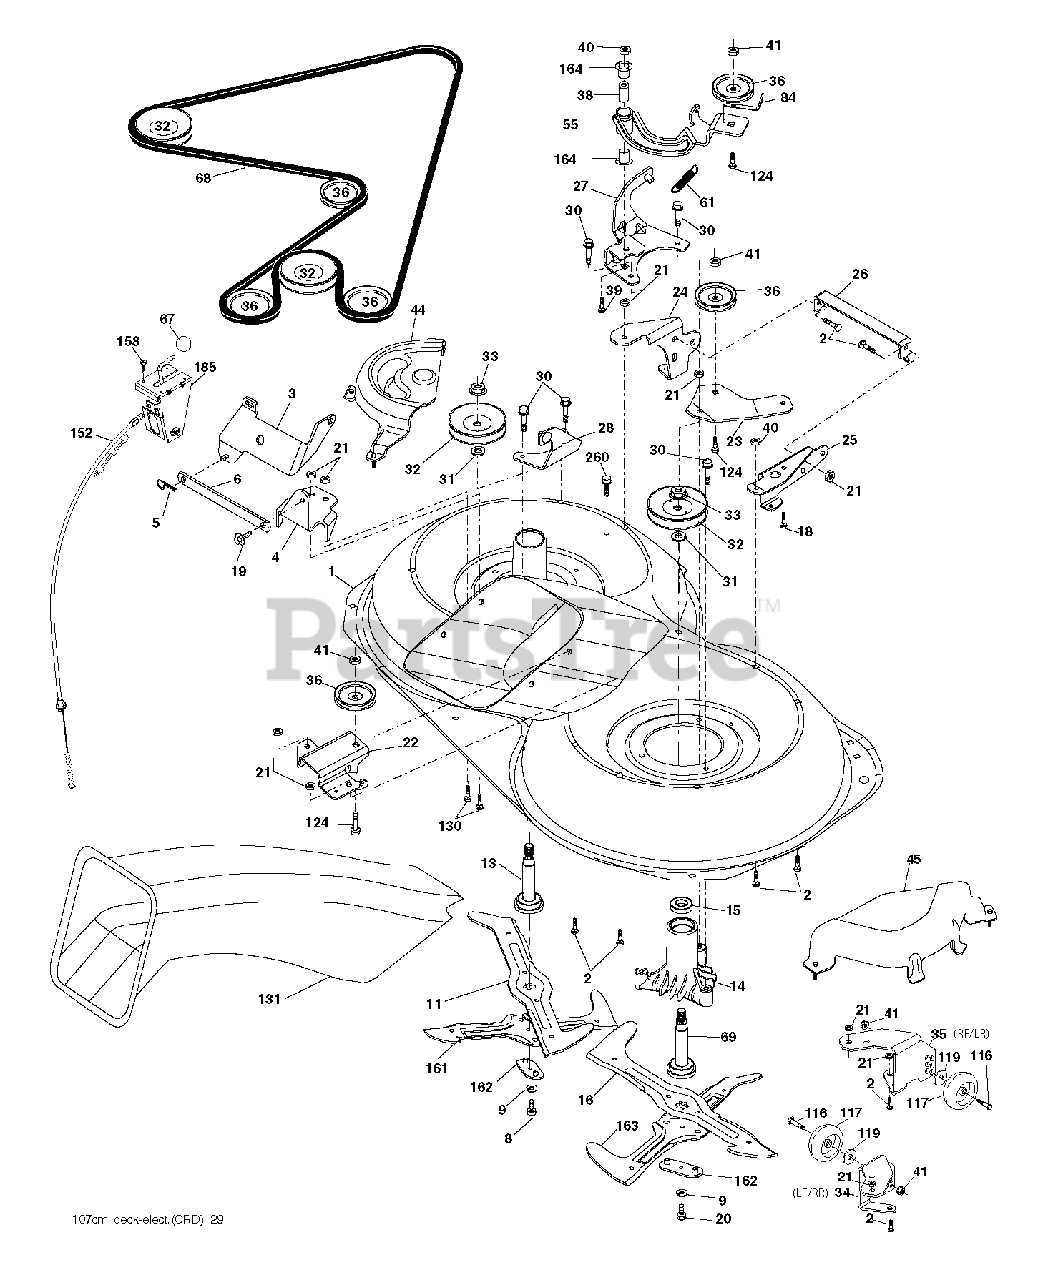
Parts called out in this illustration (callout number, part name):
2	BOLT
3	BRACKET.ASM.BAR.SWAY.CHASS
5	RETAINER-SPRNG RB
6	BAR SWAY
8	Bolt, 3/8-24 X 1.25 Gr8
9	LOCKWASHER
11	BLADE.3N1.LH.CRD
13	SHAFT ASM VENT
16	BLADE.3N1.RH.CRD
19	BOLT SHD 5/16-18
20	BOLT.3/8-24X1.25GR8. LHTHRD
21	LOCKNUT
22	BRACKET
23	BRACKET
27	BRACKET
30	SCREW, WASHER HEAD
31	WASHER.SPACER.MANDREL
33	NUT.FLANGE.LOCK.TOP
36	PULLEY.IDLER.4.25
40	LOCKNUT
41	NUT LOCK FLG 3/8-16 UNC
67	KNOB T (3/8 HOLE)
68	HEX-BELT 107 MOWER
69	SHAFT.ASM.W/LWR.BRG.RH.THREAD
84	KEEPER, BELT IDLER
116	BOLT.SHOULDER.3/8-16X3-5/8
117	WHEEL. GUAGE RALLY
124	BOLT.3/8-16X1.50
158	SCREW
164	BRNG T
185	HEAD ASM. CABLE CLUTCH
260	SCREW 3/8-16X1/2
